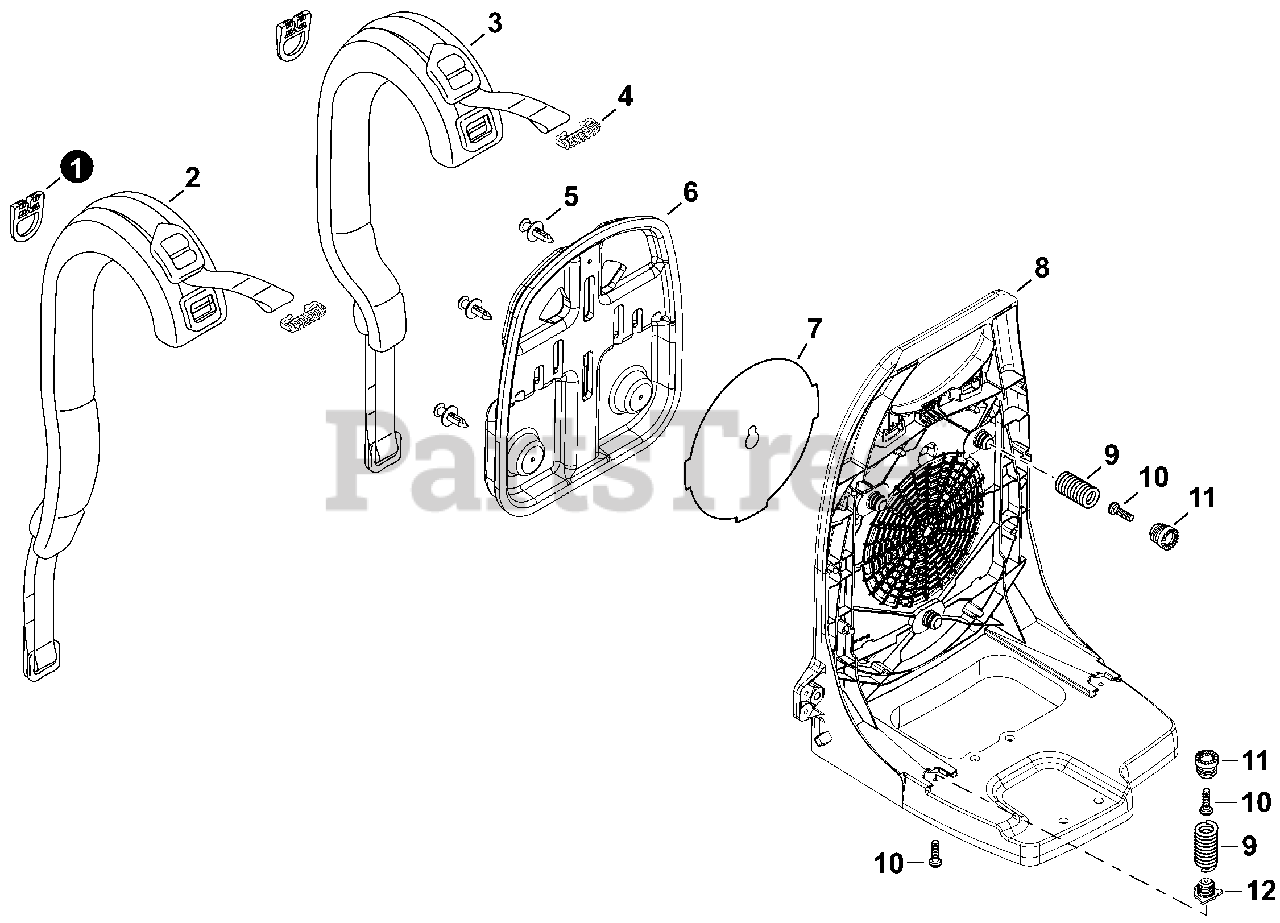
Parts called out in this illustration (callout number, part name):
1	BUCKLE, HARNESS
2	SHOULDER STRAP - LEFT
3	SHOULDER STRAP - RIGHT
6	CUSHION, BACKPACK
7	INSERT, COLD WEATHER
8	FRAME, BACKPACK
9	SPRING, COMPRESSION
10	BOLT, TORX 5x20
11	HOLDER, SPRING
12	HOLDER, SPRING
